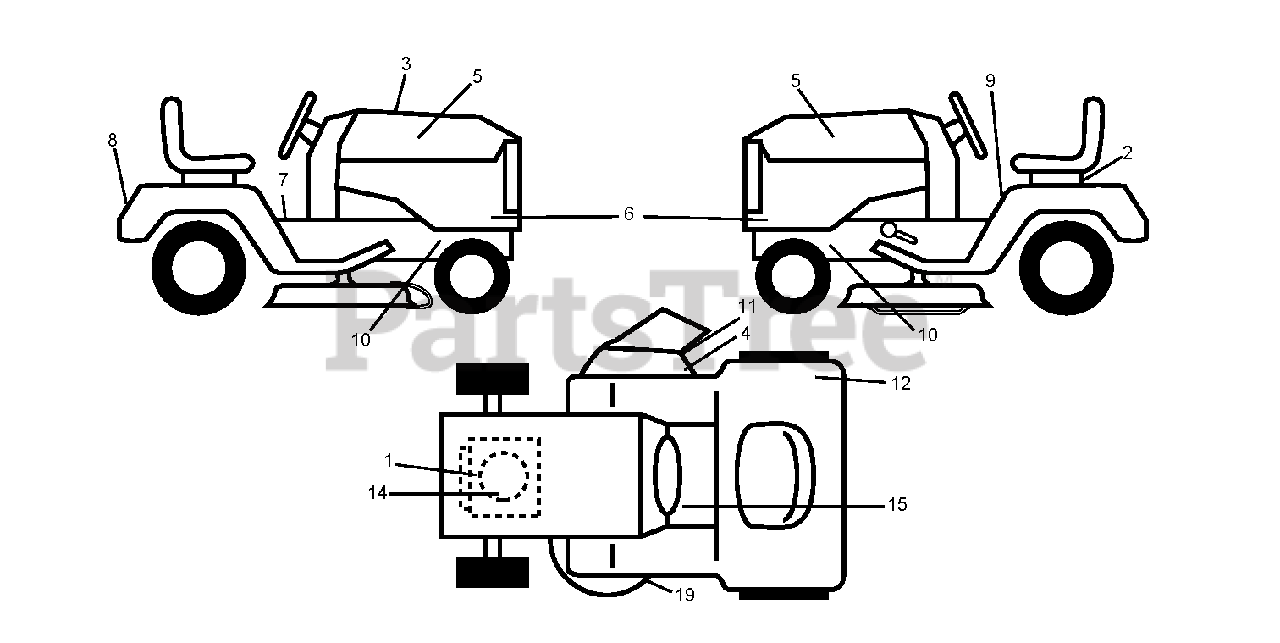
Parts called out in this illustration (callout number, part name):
2	DECAL BTRY SYMBOLS
4	DECAL, DEFLECT WARNING
7	DECAL PARK BRAKE
11	DECAL.INTERNATIONL.CUTFINGER
19	DECAL.V-BELT.SCHEMATIC.36/38/9
